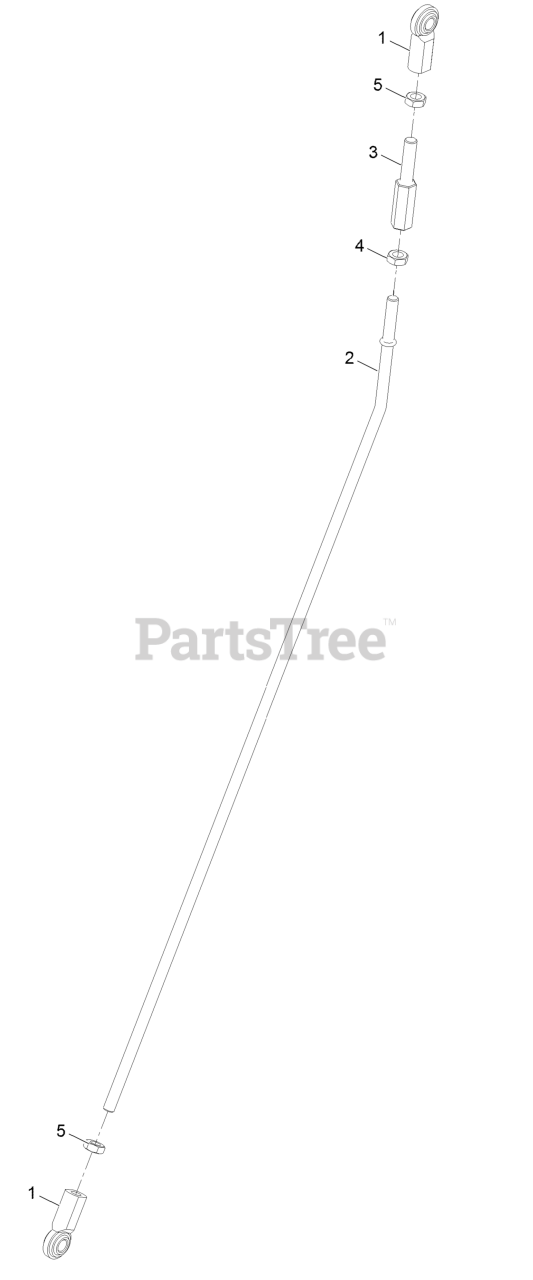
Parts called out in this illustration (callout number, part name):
1	Balljoint
2	Linkage-Motion
3	Rod-Adjustment
4	Nut-Jam 3/8-24 LH
5	Nut-Jam 3/8-24
